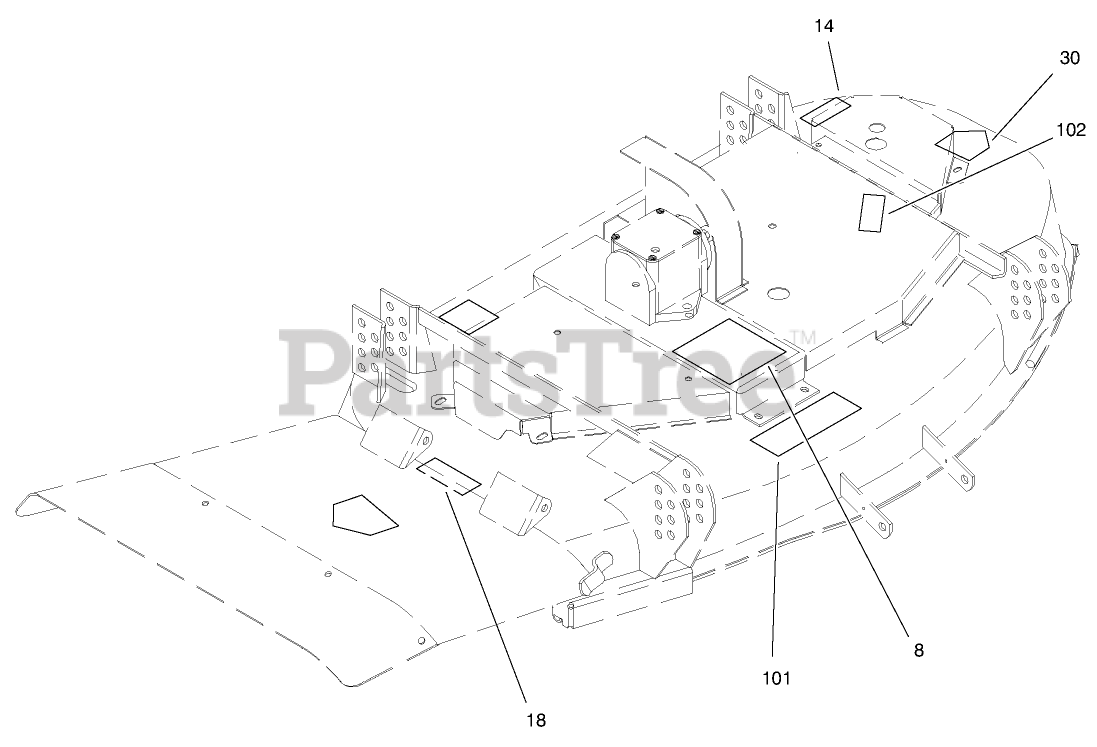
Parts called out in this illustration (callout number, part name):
8	DECAL-44 INCH
14	DECAL-TORQUE, BLADE BOLT
18	DECAL-WARNING, DEFLECTOR
30	DECAL-DANGER
101	DECAL-DANGER
